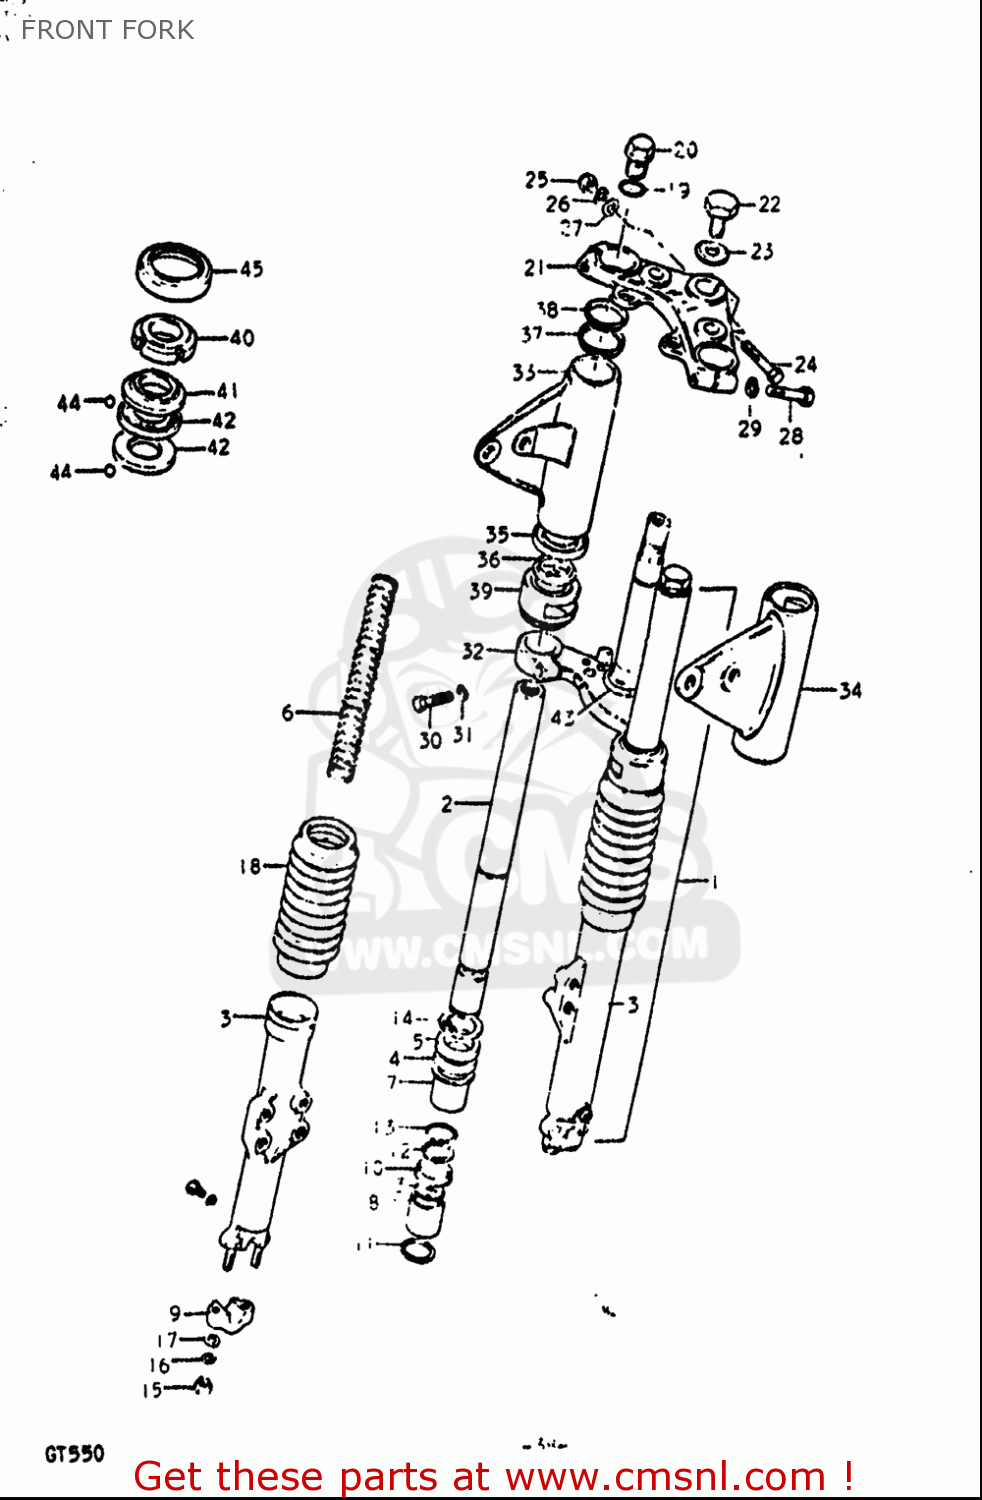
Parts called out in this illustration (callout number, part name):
4	SEAL,OIL 35X48X11
5	SEAL,OIL 35X48X11
9	HOLDER,AXLE
15	NUT
16	WASHER,LOCK
17	WASHER
18	BOOT
19	O RING
20	CAP,INNER TUBE
24	BOLT
25	NUT
26	WASHER,LOCK
27	WASHER
28	BOLT
29	WASHER,LOCK
30	BOLT
31	WASHER,LOCK
35	GUIDE
36	CUSHION,HEADLAMP BRACKET
37	GUIDE
38	CUSHION,HEADLAMP BRACKET UPR
40	NUT,STEERING STEM(25X44X10)
41	LACE,STEERING OUTER UPR
42	LACE,STEERING INNER LWR
43	RACE,STEERING OUTER LWR
44	BALL
45	DUST SEAL,STEERING UPR
